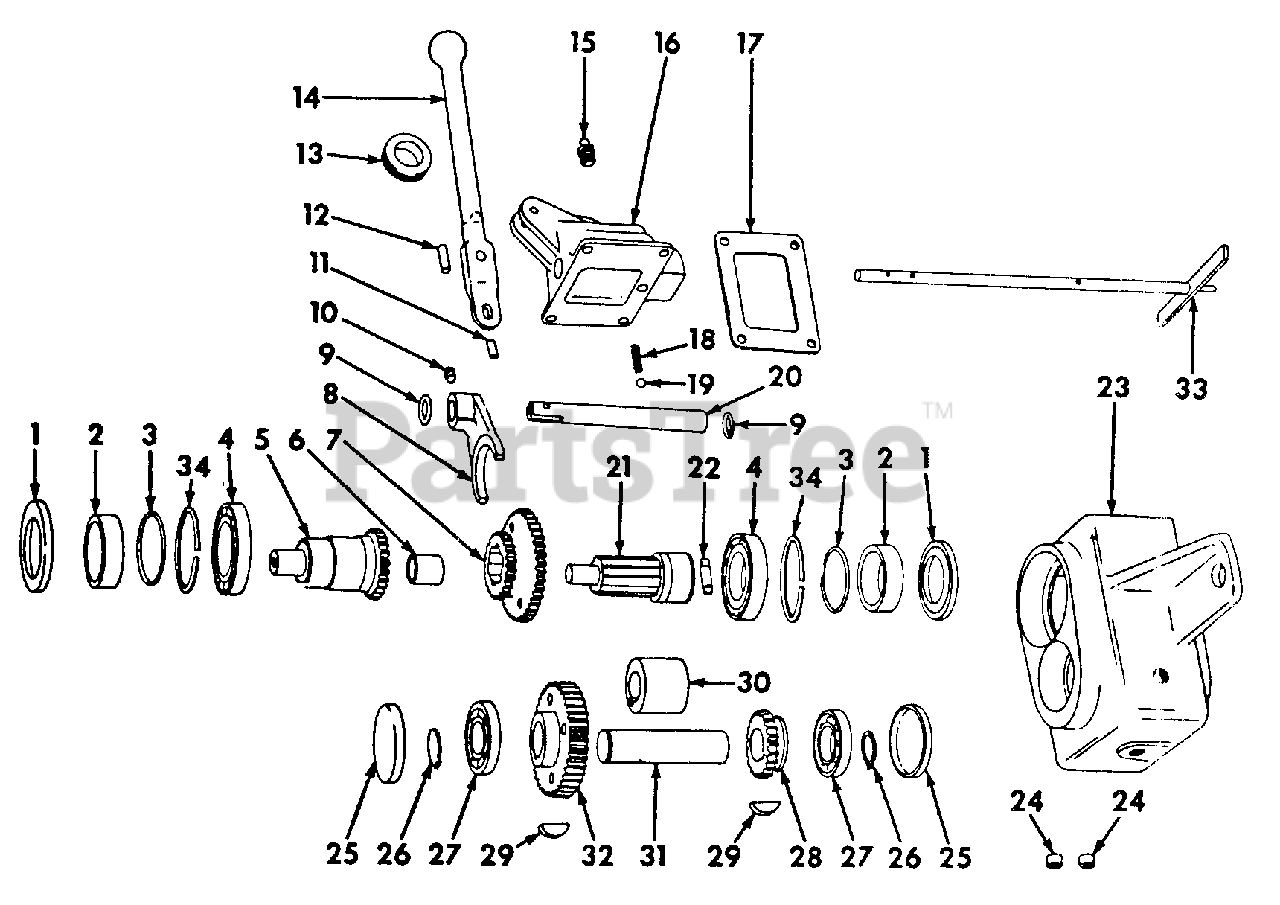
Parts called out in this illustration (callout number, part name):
3	O-Ring, 1 X 1-1/8 X 1/16
4	Bearing Assy, Ball
5	Shaft w/Gear & Needle Bearing Input
6	Bearing, Needle
8	Fork, Shifter
9	O-Ring, 1/2 X 11/16 X 3/32
10	Screw, 1/4-20 X 1/4 Hex-Soc-Hd Set
11	Pin, 3/16 X 3/4 Hv-Coiled Spring
12	Pin, 3/16 X 1/2 Hv-Coiled Spring
14	Lever, Gear Shift
15	Plug, Breather
16	Cap w/O-Ring, Shifter
18	Spring, Poppet Ball
19	Ball, 1/4 Steel
21	Shaft, Output
23	Box W/Plugs, Gear
24	Plug, 1/8-27 Automotive Hex-Soc-Hd Pipe
25	Plug, Expansion
26	Ring, Retainer
27	Bearing Assy, Ball
29	Key, 3/16 X 3/4 Woodruff 9
31	Shaft, Lower
33	Shaft Assy, Clutch
34	Ring, Upper Shaft Brg Snap
